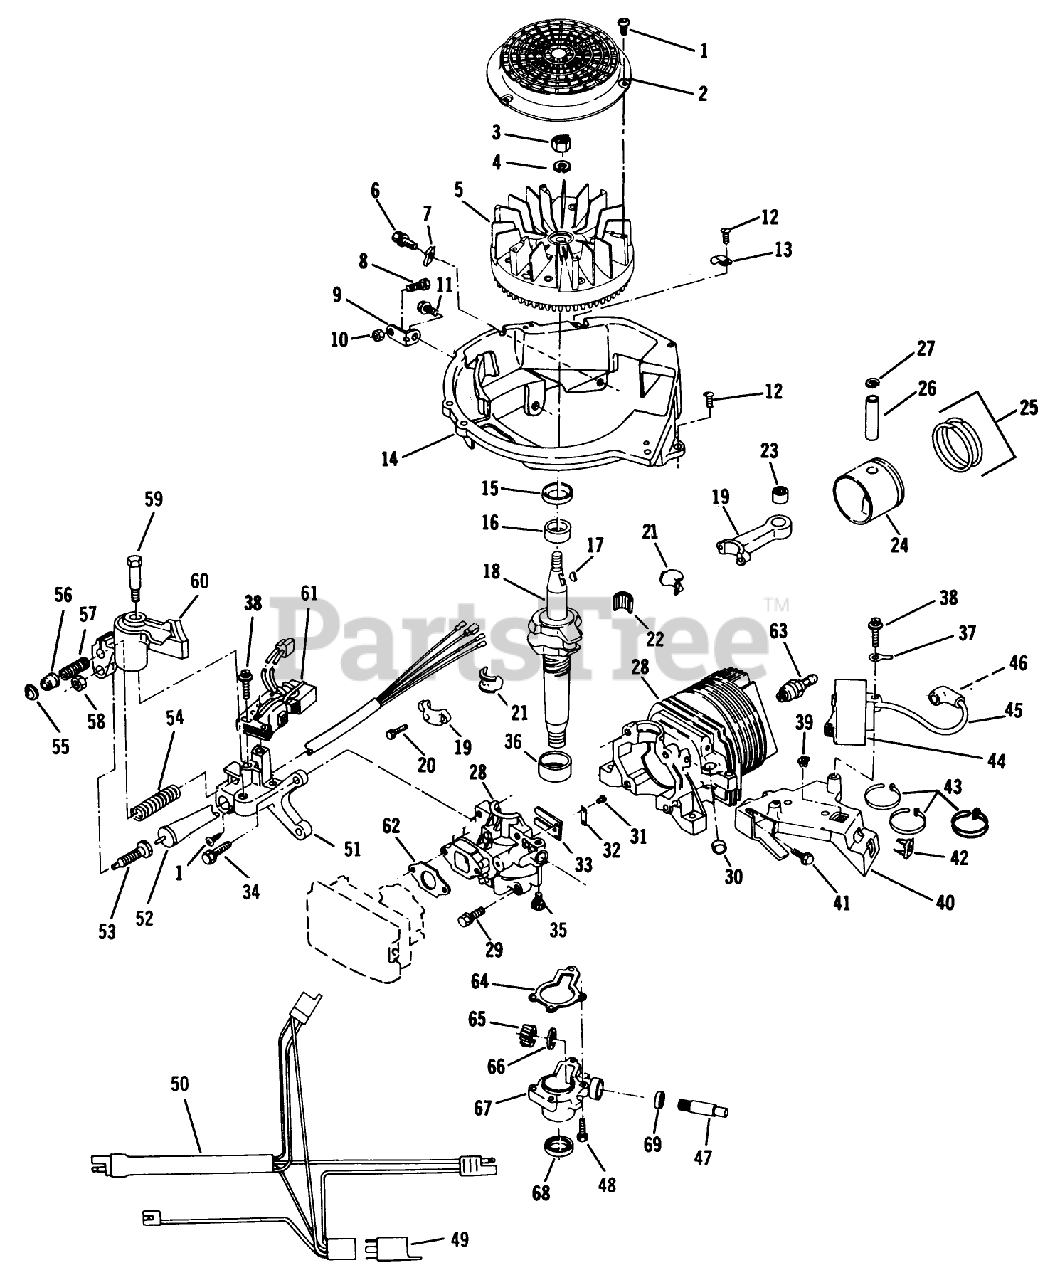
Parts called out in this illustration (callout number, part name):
1	SCREW F
2	SCREEN F'WHEEL S
3	NUT
5	FLYWHEEL ASSY F
6	SCREW-SEMS
8	BOLT F
10	NUT-LOCK F
12	SCREW F
14	BASE SHROUD F
16	BEARING V
17	KEY
20	SCREW-HSH
21	LINER ASM
23	BEARING AY F
27	RING-RETAINING
29	SCREW S
30	PLUG-CORE VF
32	PLATE-BACKUP, REED
36	BEARING S
37	TERMINAL S
39	NUT-CLIP
42	NUT-CLIP
45	HT LEAD&COVER XEV
51	BRACKET F
51	BRACKET-BRAKE F
53	PLUNGER S
54	SPRING-BRAKE
55	RETAINER S
56	ACTUATOR-LEVER, BRAKE
57	SPRING
62	GASKET CARB S
64	GASKET S
65	GEAR, DR SHAFT S
66	THRUST WASHER
68	SEAL-OIL
69	SEAL S
